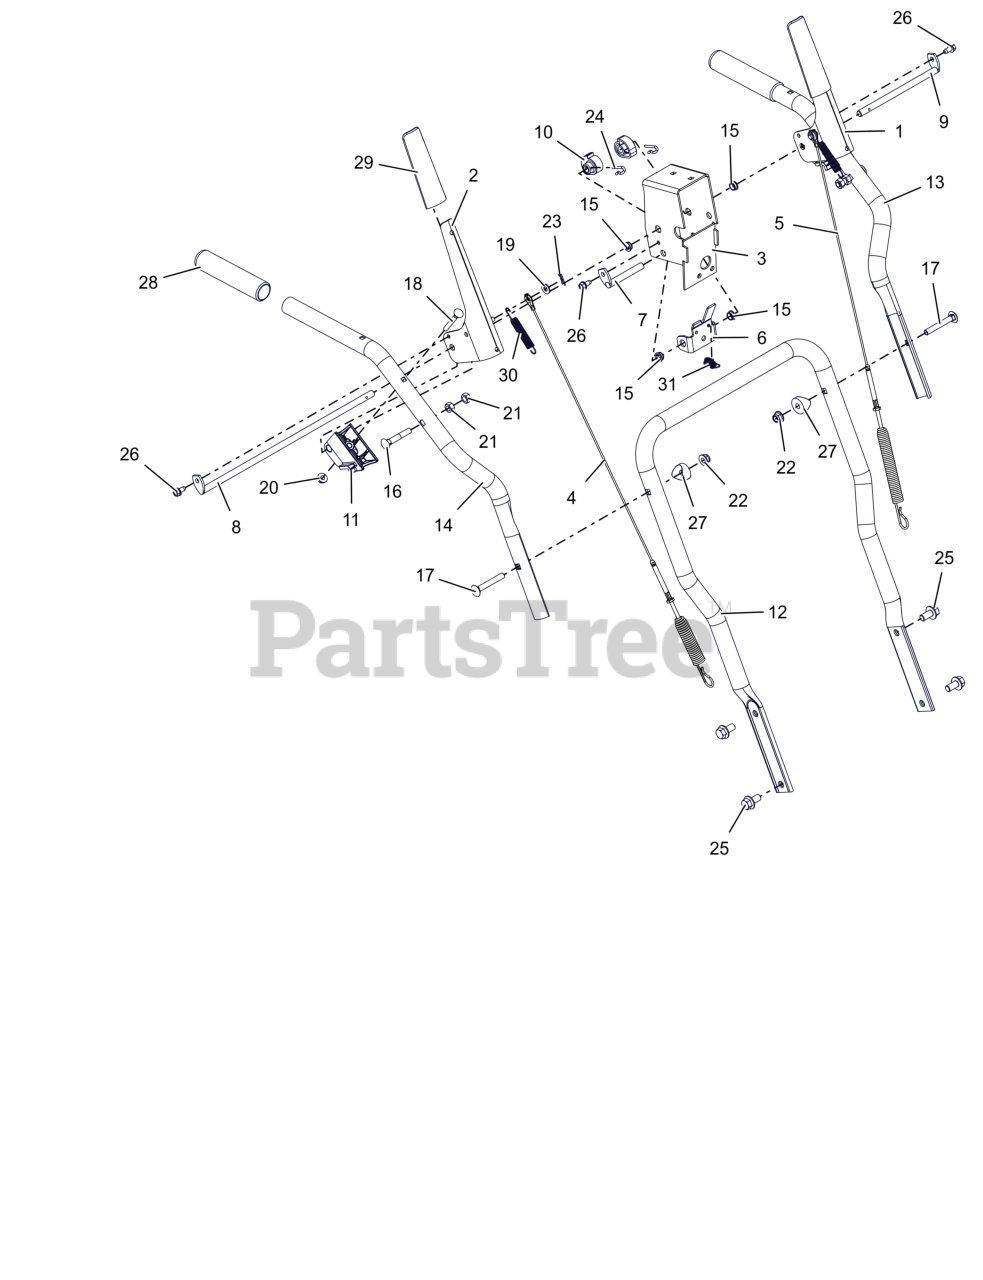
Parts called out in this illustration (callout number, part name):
1	LEVER, CLUTCH-LH
2	LEVER, CLUTCH-RH
3	WELDMENT, BRACKET INTERLOCK
4	CABLE, AUGER (DELUXE & PRO)
5	CABLE, UPPER TRACTION
6	BRACKET, INTERLOCK ARM
7	ROD, PIVOT - INTERLOCK
8	ROD, PADDLE MOUNT - LONG
9	ROD, PADDLE MOUNT - SHORT
10	CAM, INTERLOCK
11	BLOCK, CLUTCH PADDLE
12	HANDLEBAR, LOWER SMALL DASH (BLACK)
13	HANDLEBAR, UPPER - LH (BLACK)
14	HANDLEBAR, UPPER - RH (BLACK)
15	BUSHING, POLYLINER-.38 SNAPIN
16	BLT-RDHDXLSQNK .31-18X2.0 G5YZ
17	BLT-RHSN.31-18X2.25 G5 TBZ 120
18	BLT-RDHDXLSQNK .25-20X2.0 G5YZ
19	WSHR,FLT .281X.625X.065 ZCC
20	NUT-LK-CTR-FLG .25-20 ZC120
21	NUT,LK-CTR .31-18 GA ZCC
22	NUT-NYL-FLG.31-18 GF TBZ 120WR
23	PIN, HAIR #178 .06X.77 ZCC
24	PIN, SPRING CLIP
26	SCR-TAP .25-20X.50 HWH ZCC
27	SPACER, HANDLEBAR
28	GRIP, HANDLEBAR
29	SLEEVE- CLUTCH PADDLE
30	SPRING, EXTENSION
31	SPRING-EXT .047X.438X1.45
